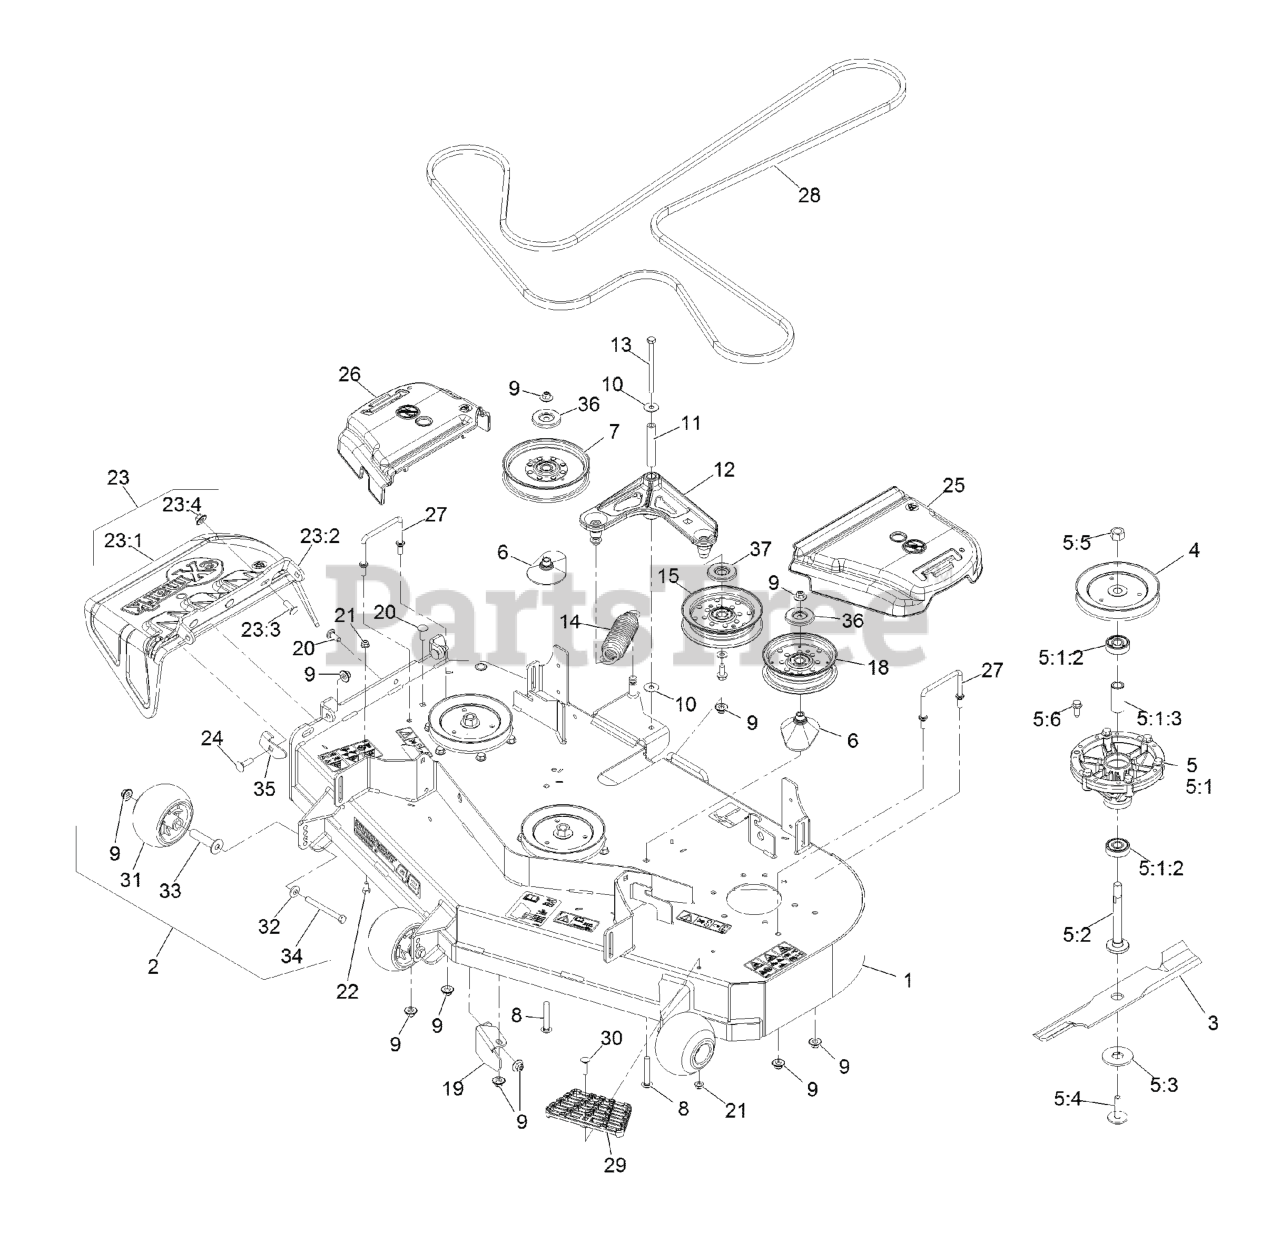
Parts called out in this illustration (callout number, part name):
1	ASM-DECK W/DECALS 483
2	KIT, ANTI-SCALP ROLLER
4	SHEAVE,BLADE DRIVE 5.90
5	ASM, CUTTER HOUSING COMPL
5:1	ASM-CUTTER HOUSING
5:1:2	BEARING
5:1:3	SPACER-BEARING
5:2	SPINDLE-HEX PILOT
5:3	WASHER-HEX BLADE DRIVE
5:4	BOLT-BLADE, SEM
5:5	NUT-HEX
5:6	SCREW-FORMING, THREAD
6	SPACER-PULLEY
7	IDLER-PULLEY, FLAT 6.00X1
8	SCREW-CARR
9	Nut-Nyloc 3/8-16 Flg
11	BUSHING
12	IDLER ARM ASM
13	SCREW-HH
14	SPRING-EXTENSION
15	IDLER-PULLEY, FLAT
18	IDLER-PULLEY, FLAT 5.00X1
19	BAFFLE,DISCHARGE 483
20	SCREW-CARR
21	NUT-HF, NI
22	SCREW-HH
23	ASM,DISCHARGE CHUTE
23:1	CHUTE,DISCHARGE
23:2	BRACKET,DISCHARGE CHUTE
23:3	SCREW-CARR
23:4	Nut-Nyloc 3/8-16 Flg
24	BOLT-CARR
25	COVER-BELT, LH
26	COVER-BELT, RH
27	WIREFORM-COVER
28	BELT-V
29	STEP-DECK
30	Bolt-Carriage 5/16-18 X 1 1/4
31	ROLLER-SCALP, ANTI
32	WASHER-BELLEVILLE
33	AXLE, ROLLER
34	SCREW-HH 3/8-16 X 3 3/4 GR 8
35	STOP-DISCHARGE CHUTE
36	SHIELD-DUST
37	SHIELD-GUARD, DUST
